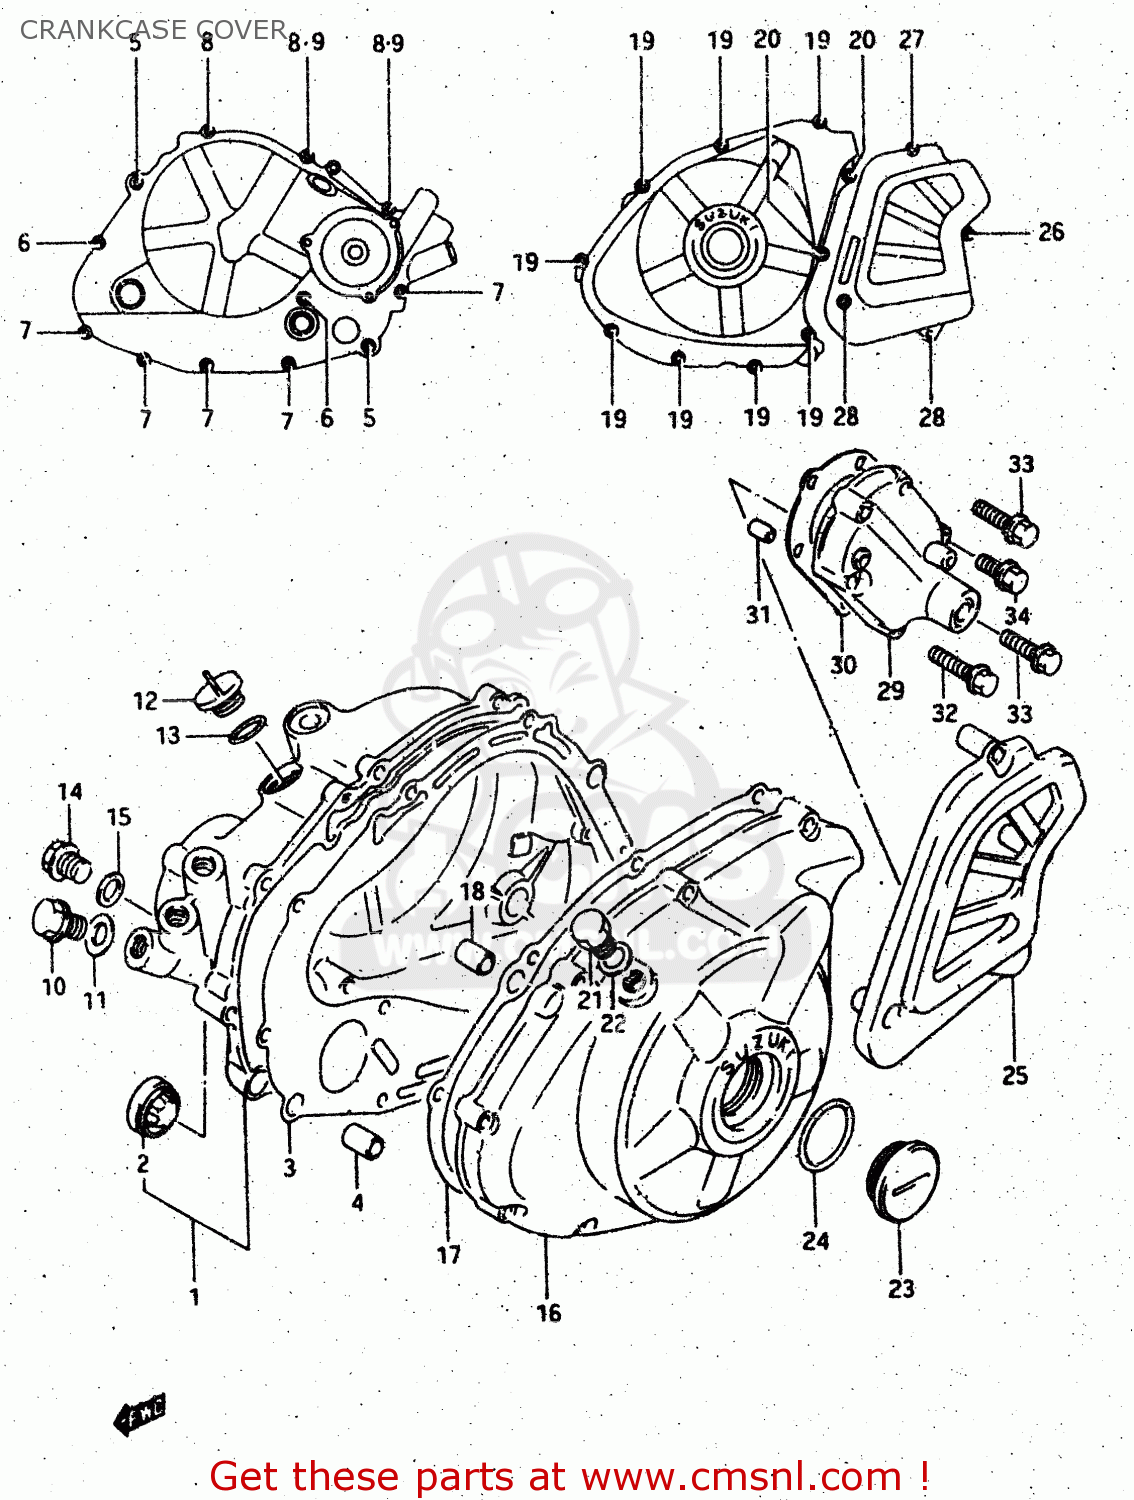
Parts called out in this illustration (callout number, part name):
1	COVER,CLUTCH
2	LENS,OIL LEVEL CHECK
3	GASKET,CLUTCH COVER
4	PIN
5	BOLT 6X50
6	BOLT 6X40
7	BOLT 6X35
8	BOLT 6X25
9	GASKET(5.8X13X1.2) (NAS)
10	PLUG(14X12)
11	GASKET(14X19.2X2) (NAS)
12	PLUG
13	O RING(D:3.1,ID:16.8)
14	PLUG(14X12)
15	GASKET(14X19.2X2) (NAS)
16	COVER,MAGNETO
17	GASKET,MAGNETO COVER (MCA)
18	PIN
19	BOLT 6X30
20	BOLT 6X25
21	PLUG(12X9)
22	GASKET(12.1X16.2X3.7) (NAS)
23	PLUG
24	O RING(D:3.1,ID:32.7)
25	COVER,ENGINE SPROCKET
26	BOLT
27	BOLT 6X35
28	BOLT 6X20
29	COVER,GEAR SHIFT
30	GASKET,GEAR SHIFT COVER (MCA)
31	PIN
32	BOLT 6X35
33	BOLT 6X30
34	BOLT 6X20
